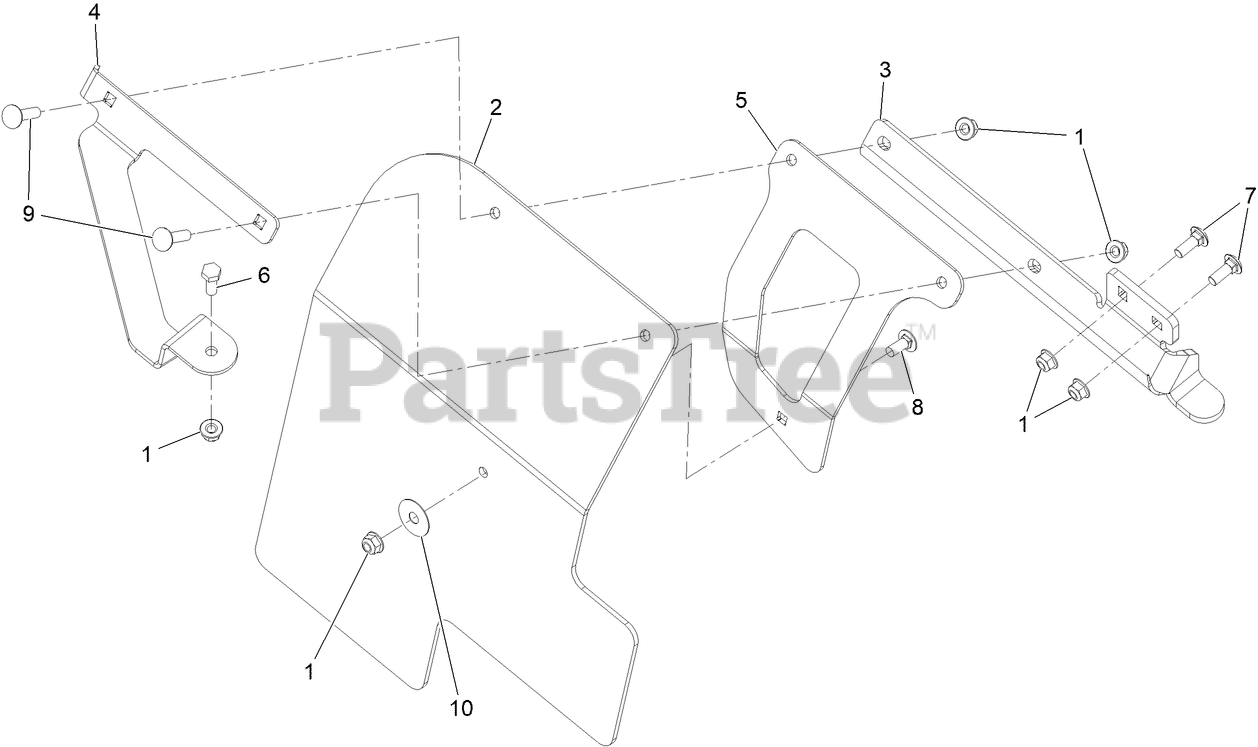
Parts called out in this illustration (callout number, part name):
1	NUT-HF, NI
2	RH MUD FLAP
3	PLATE-RH MUD FLAP BRACKET
4	PLATE-RH MUD FLAP SUPPORT
5	SUPPORT, RH MUD FLAP
6	SCREW-HH
7	SCREW-CARR
8	SCREW-CARR
9	SCREW-CARR
10	WASHER-PLAIN
